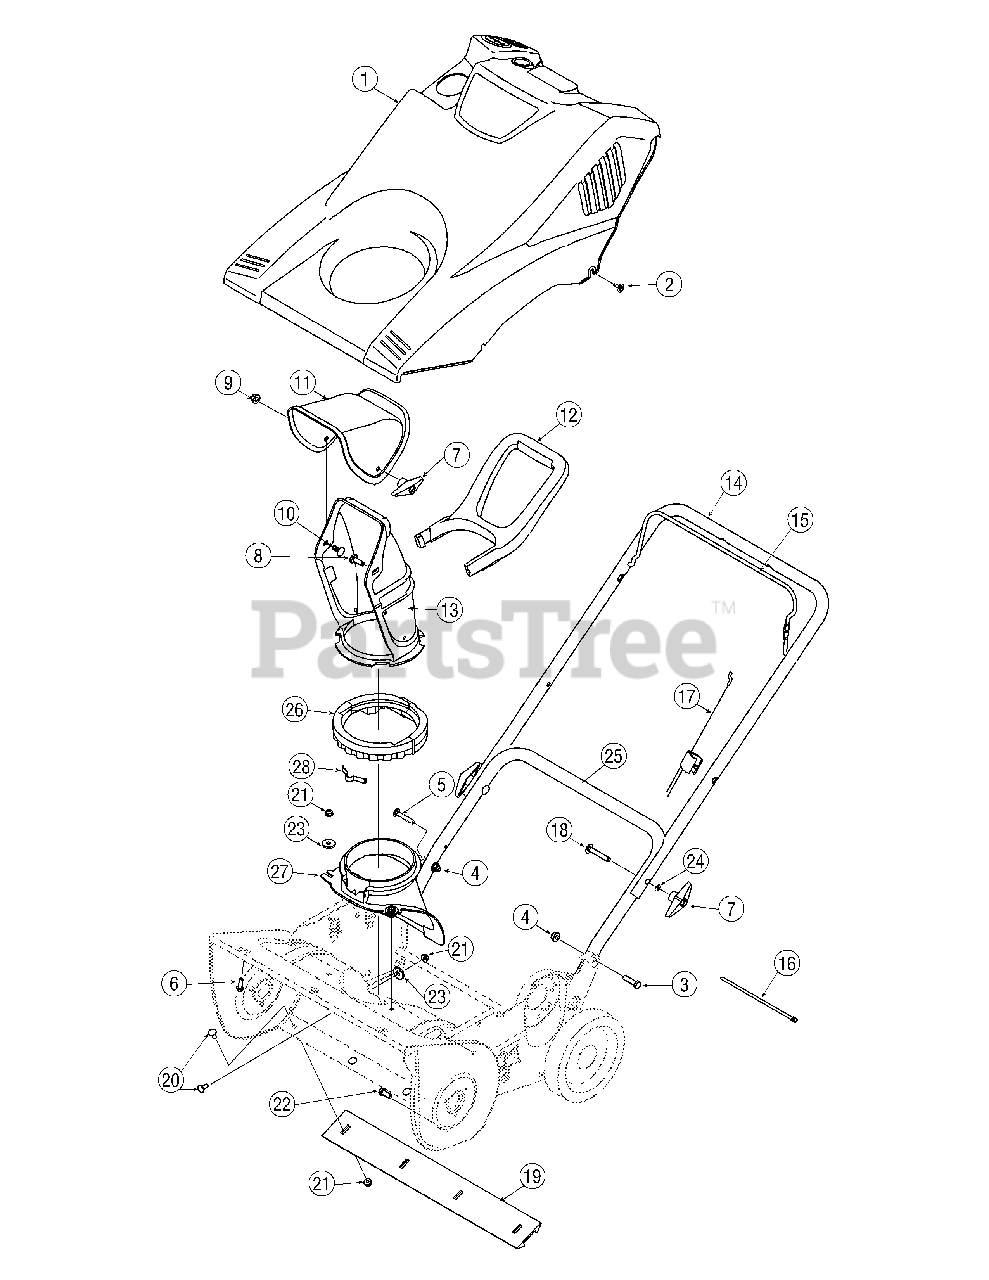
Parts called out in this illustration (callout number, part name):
1	Shroud
2	Hex Screw, 10-16 x .625
3	Hex Flange Screw, 5/16-18 x 1.25
4	Flange Lock Nut, 5/16-18
5	Hex Flange Screw, 5/16-18 x 1.50
6	Hex Screw, 1/4-15 x .750
7	Wing Nut, 5/16-18
8	Carriage Bolt, 5/16-18 x 1.00
9	Flange Lock Nut, 5/16-18
10	Carriage Bolt, 5/16-18 x .750
11	Upper Chute
12	Chute Handle
13	Lower Chute
14	Upper Handle
15	Bail Control
16	Cable Tie, 3/16 x .05 x 7.4
17	Clutch Cable
18	Carriage Bolt, 5/16-18 x 2.00
19	Shave Plate, 21"
20	Carriage Screw, 1/4-20 x .62
21	Flange Lock Nut, 1/4-20
22	Hex Screw, 5/16-18 x .75
23	Flat Washer, .265 x .938 x .120
24	Speed Nut, .3125
25	Lower Handle
26	Lower Chute Ring
27	Chute Adapter
28	Chute Adjustment Spring
